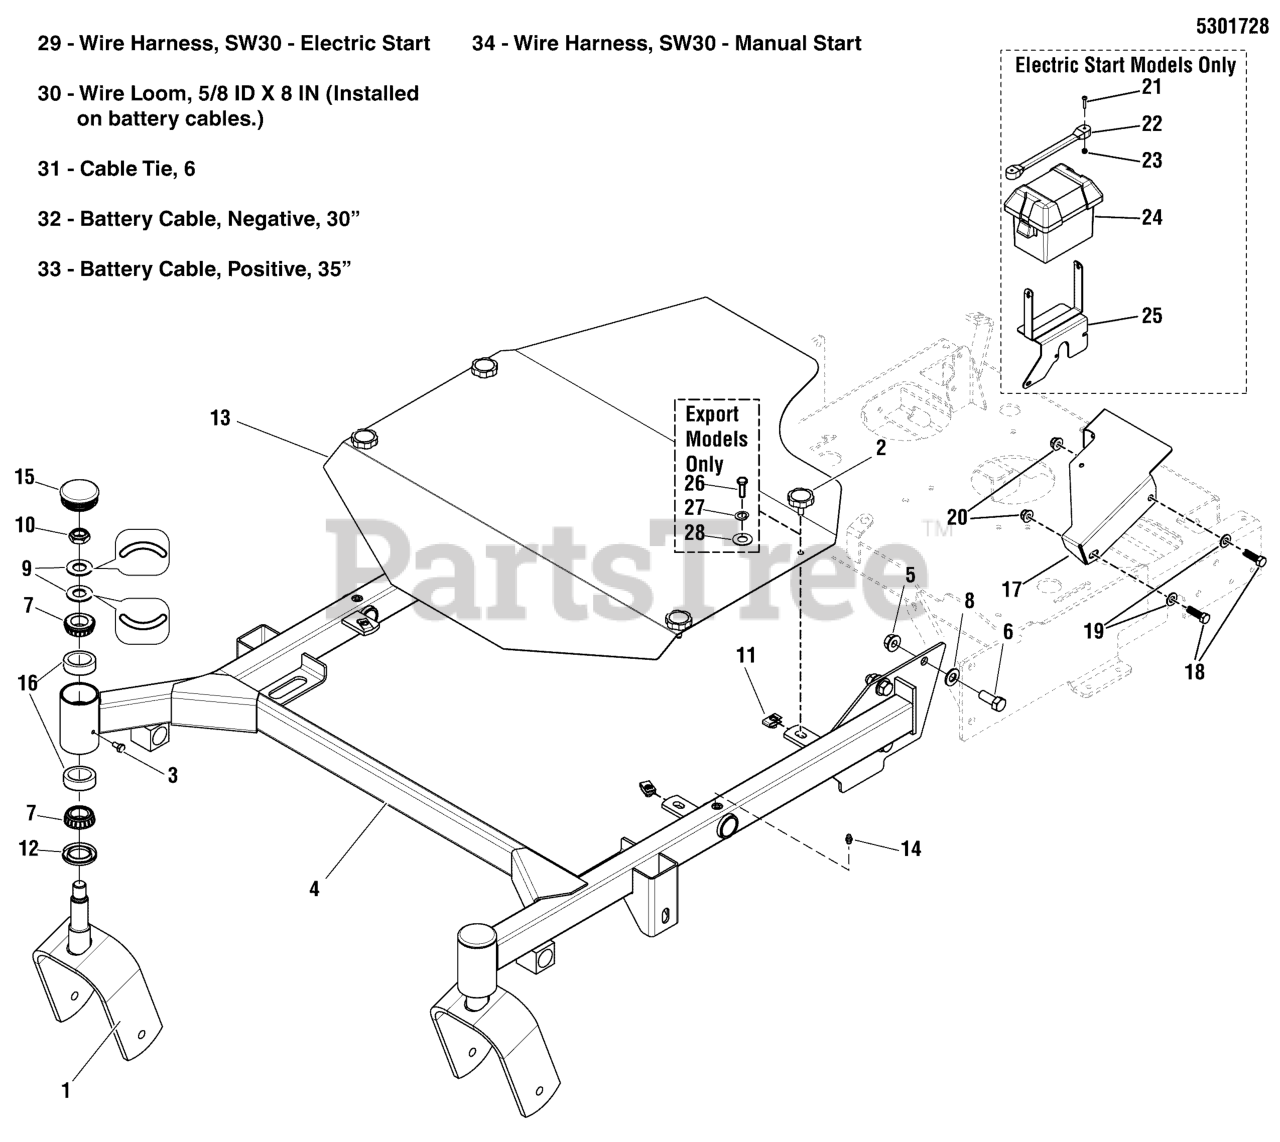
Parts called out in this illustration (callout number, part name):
1	WELD., FRONT CASTER YOKES - RED
2	KNOB, 5/16-18 X 1.00, ROSETTE, BLK
3	BOLT, 1/4-28 X 1/2, GD5 YZ
5	NUT, Hex Flange, Nylock, 1/2-13
6	BOLT, 1/2-13 X 1-1/4 GD5 CZ
7	BEARING, TAPERED ROLLER, 1
8	WASHER, 1/2 SAE
9	WASHER, BELLEVILLE - 1.500 X .755
10	NUT, 3/4-16, HEX JAM NYLON LOCK
11	BODY CLIP 5/16-18 X 1/4" MAT
12	SEAL, GREASE
14	GREASE FITTING, 1/4-28 STRAIGHT
15	CAP, GREASE, LOW PROFILE
16	CUP, BEARING (SV)
17	GUARD, LEFT, SW30-52 - RED
18	BOLT, 3/8-16 X 1" GD5 CZ
19	WASHER, 3/8 SAE
20	NUT, 3/8-16 HEX NYLOCK FLANGE
21	SCREW, #10-24 X 1 RS, CZ
22	STRAP, RUBBER
23	NUT, #10-24, HEX NYLON FLANGE
24	BATTERY BOX, W/ DRAIN HOLE
25	WELD, BATTERY MOUNT, SW30-61 - RED
26	BOLT, 5/16-18 X 1, GD5 YZ
27	WASHER, 5/16 LOCK CZ
28	WASHER, 5/16" SAE
29	WIRE HARNESS, SW30 KAV ELEC
30	WIRE LOOM, 5/8 ID X 8 IN
31	CABLE TIE, 6
32	CABLE, BATTERY, NEGATIVE, 30"
33	BATTERY CABLE, POSITIVE, 35
34	WIRE HARNESS, SW30 - MANUAL START
